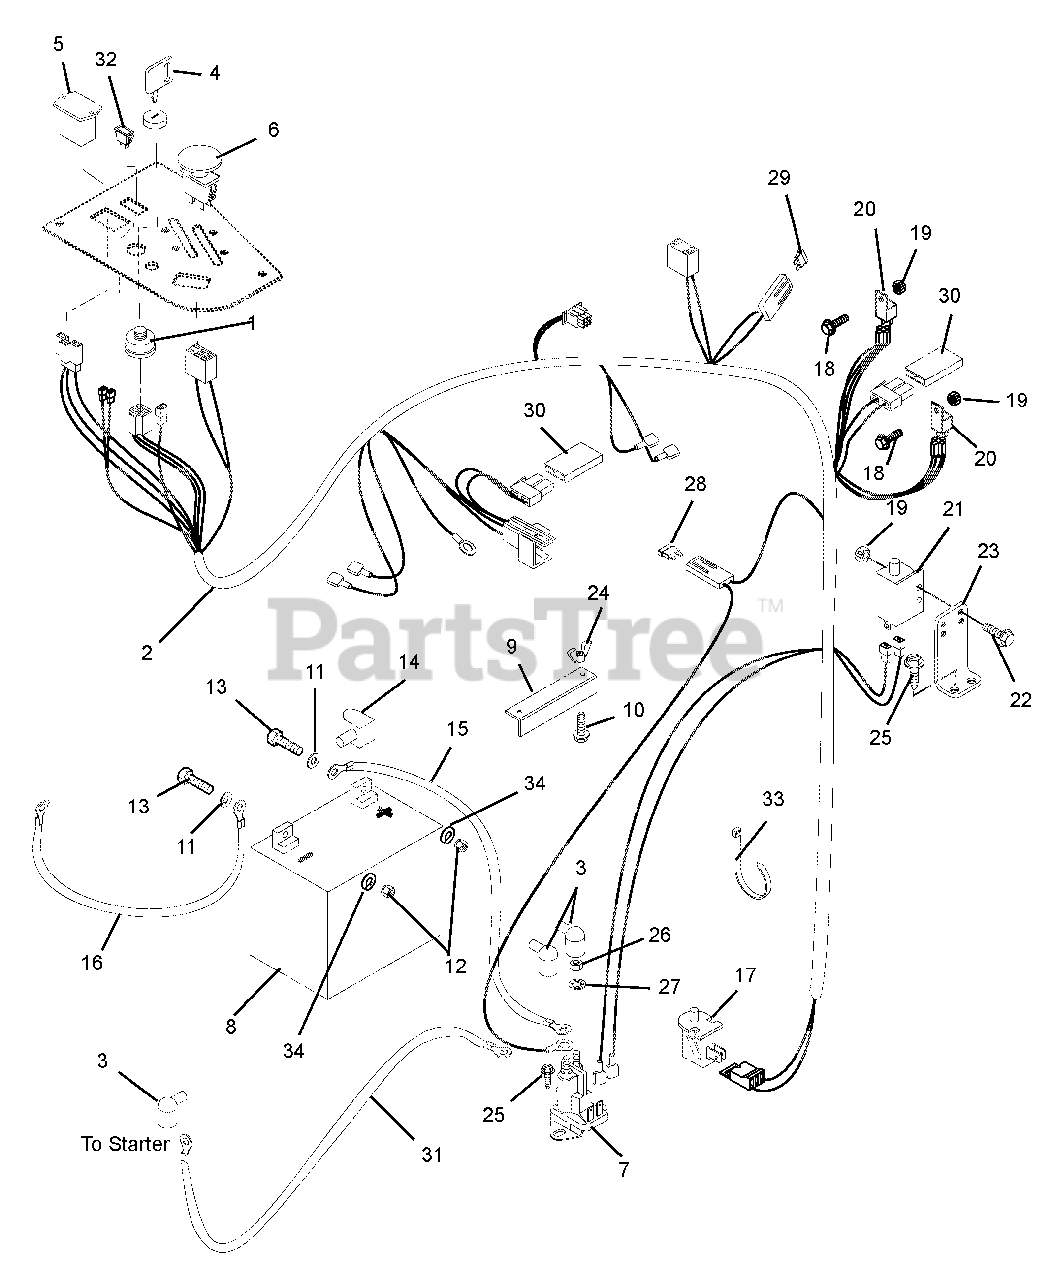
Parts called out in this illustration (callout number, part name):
1	Key Switch
2	Harness, IZ 6-Pin Wiring
3	Boot, Eyelet Terminal
4	Key with Shield
5	Hour Meter – Digital
6	Switch, Clutch With Retainer Ring
7	Solenoid
9	Hold Down
10	Bolt, Round Head Square Neck .25-20 x 7.50
11	Washer, Flat Steel .281 x .620 x .065
12	Nut, Hex .25-20
13	Bolt, Hex .25-20 x .75 Grade 5
14	Insulator
15	Cable, Positive Battery 9.00"
16	Cable, Ground
17	Switch, Seat
18	Screw, Machine 10-24 x .50 Hex Washer Head
19	Nut, Locking Nylon 10-24 With Insert
20	Relay (Included with Harness)
21	Switch, Single Pole
22	Screw, Machine 10-24 x .75 Hex Washer Head
23	Mount, Brake Switch
24	Nut, Locking Wing .25-20
25	Screw, Tapping .25-20 x .50 Hex Washer Head
26	Nut, Jam .31-24
27	Washer, Locking .31 x .078 Regular
28	Fuse, 25 Amp (Included with Harness)
29	Fuse, 20 Amp
30	Diode, Connector Shell
31	Cable, Starter
32	Switch, Blank
33	Cable Tie
34	Washer, Lock .25 x .062
